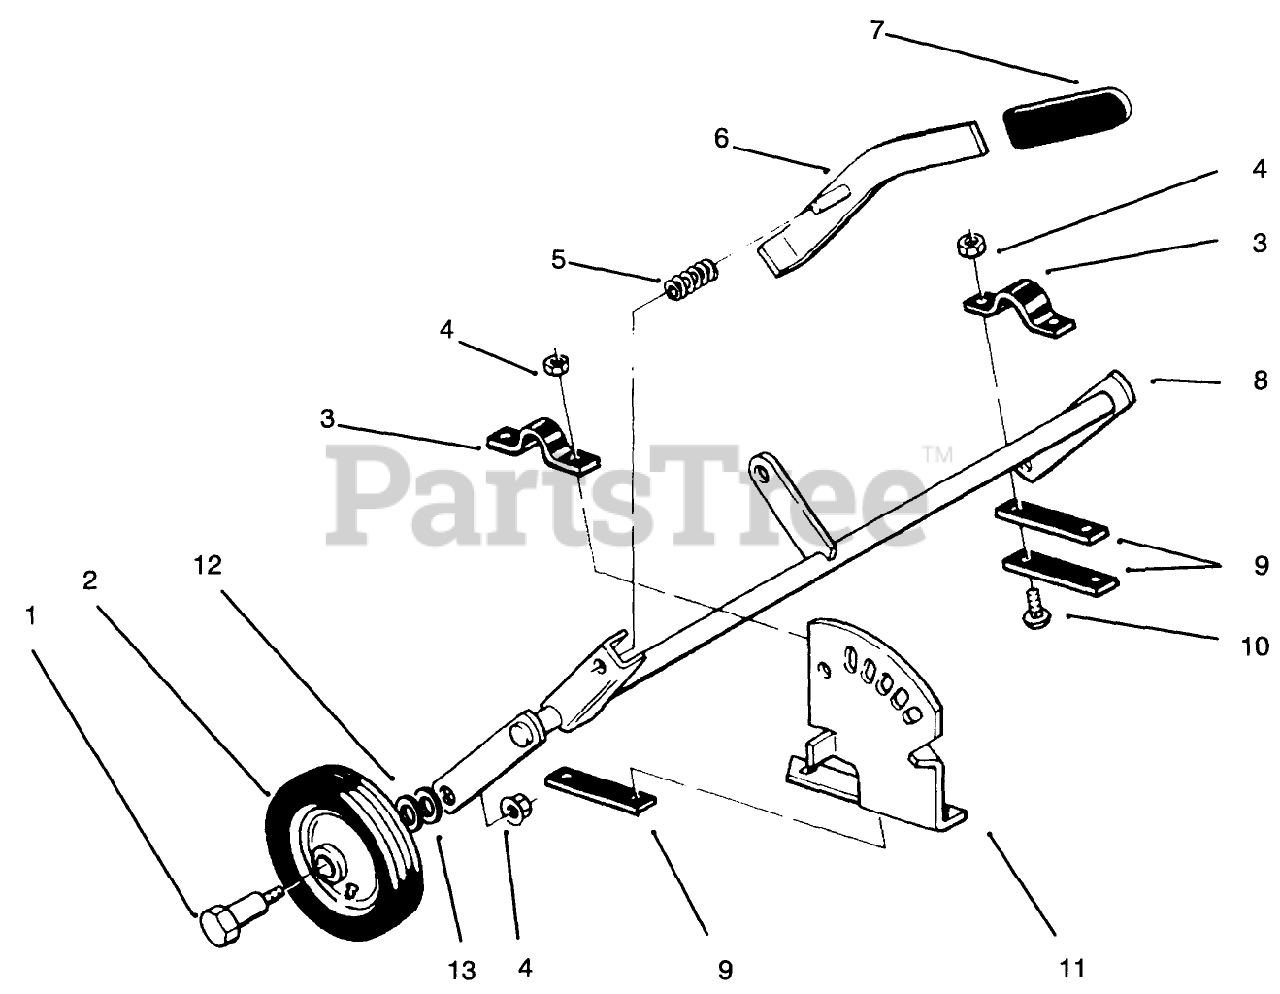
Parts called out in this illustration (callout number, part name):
1	BOLT-SHOULDER
2	WHEEL ASM
3	CLAMP
5	SPRING-COMPRESSION
10	BOLT-CARR
12	WASHER-FLAT
13	WASHER
